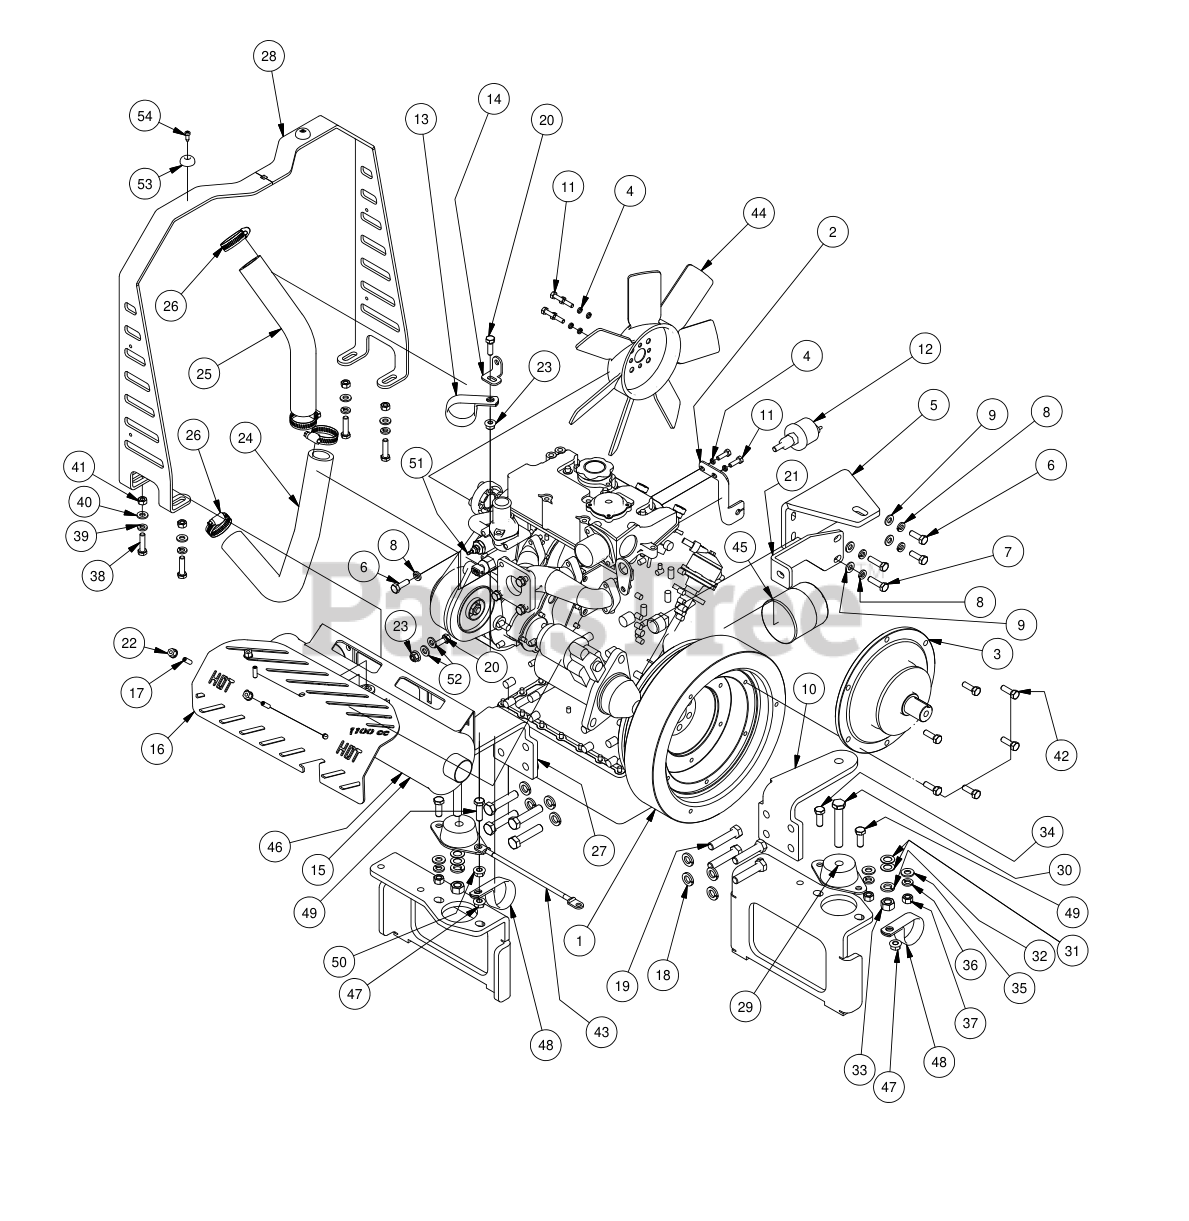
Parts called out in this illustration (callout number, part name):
1	1500cc CAT Diesel Engine
2	Diesel Throttle Bracket (4 Tier)
3	Stub Shaft
4	1/4" Lock Washer
5	Air Cleaner Support Diesel
6	M8 x 1.25 x 25mm Hex Head Bolt
7	M8 x 1.25 30mm Hex Head Bolt
8	5/16" Lock Washer
9	5/16" Flat Washer
10	Diesel Motor Side Support Right
11	6mm x 20mm Bolt
12	Pressure Sender-2012 Gauge and Up
13	Diesel Clamp 1 3/4" Vinyl
14	Diesel Radiator Hose Clamp Bracket
15	28/35hp Caterpillar Muffler
16	Diesel Muffler Guard (1500cc)
17	1/4" x 3/4" Set Screw
18	1/2" Lock Washer
19	12mm Bolt- Diesel
20	5/16" x 1" Bolt
21	Muffler Brace Diesel
22	1/4-20 Nylon Insert flange Nut
23	5/16" Flange Nut
24	Bottom Radiator Hose for Diesel
25	Top Radiator Hose for Diesel
26	1 1/8" Hose Clamp
27	Diesel Side Motor Mount (Left)
28	Hood Holder Diesel
29	Rubber Isolator
30	1/2" x 3" Hex Bolt
31	1/2" Brass Washer
32	1/2" Lock Washer
33	1/2" Hex Nut
34	3/8" x 1" Hex Bolt
35	3/8" Flat Washer
36	3/8" Lock Washer
37	3/8" Hex Nut
38	5/16" x 1 1/4" Hex Bolt
39	5/16" Lock Washer
40	5/16" Flat Washer
42	5/16-18 x 1 Button Head Bolt
43	Starter to Chassis Cable - Diesel 1500cc
44	Engine Fan - Diesel
45	CAT Oil Filter
46	Diesel Side Motor Mount Left
47	3/8 Nylock Jam Nut 1/2 Nut
48	Diesel Clamp 1 3/4" Vinyl
49	3/8" x 1 1/2" Hex Bolt
50	3/8" Flange Nut
51	Temperature Sender-2012 Gauge
52	1/4 USS Flat Washer Zinc
53	Button Bumper
54	#10 x 1/2" Self Tapping Screw
